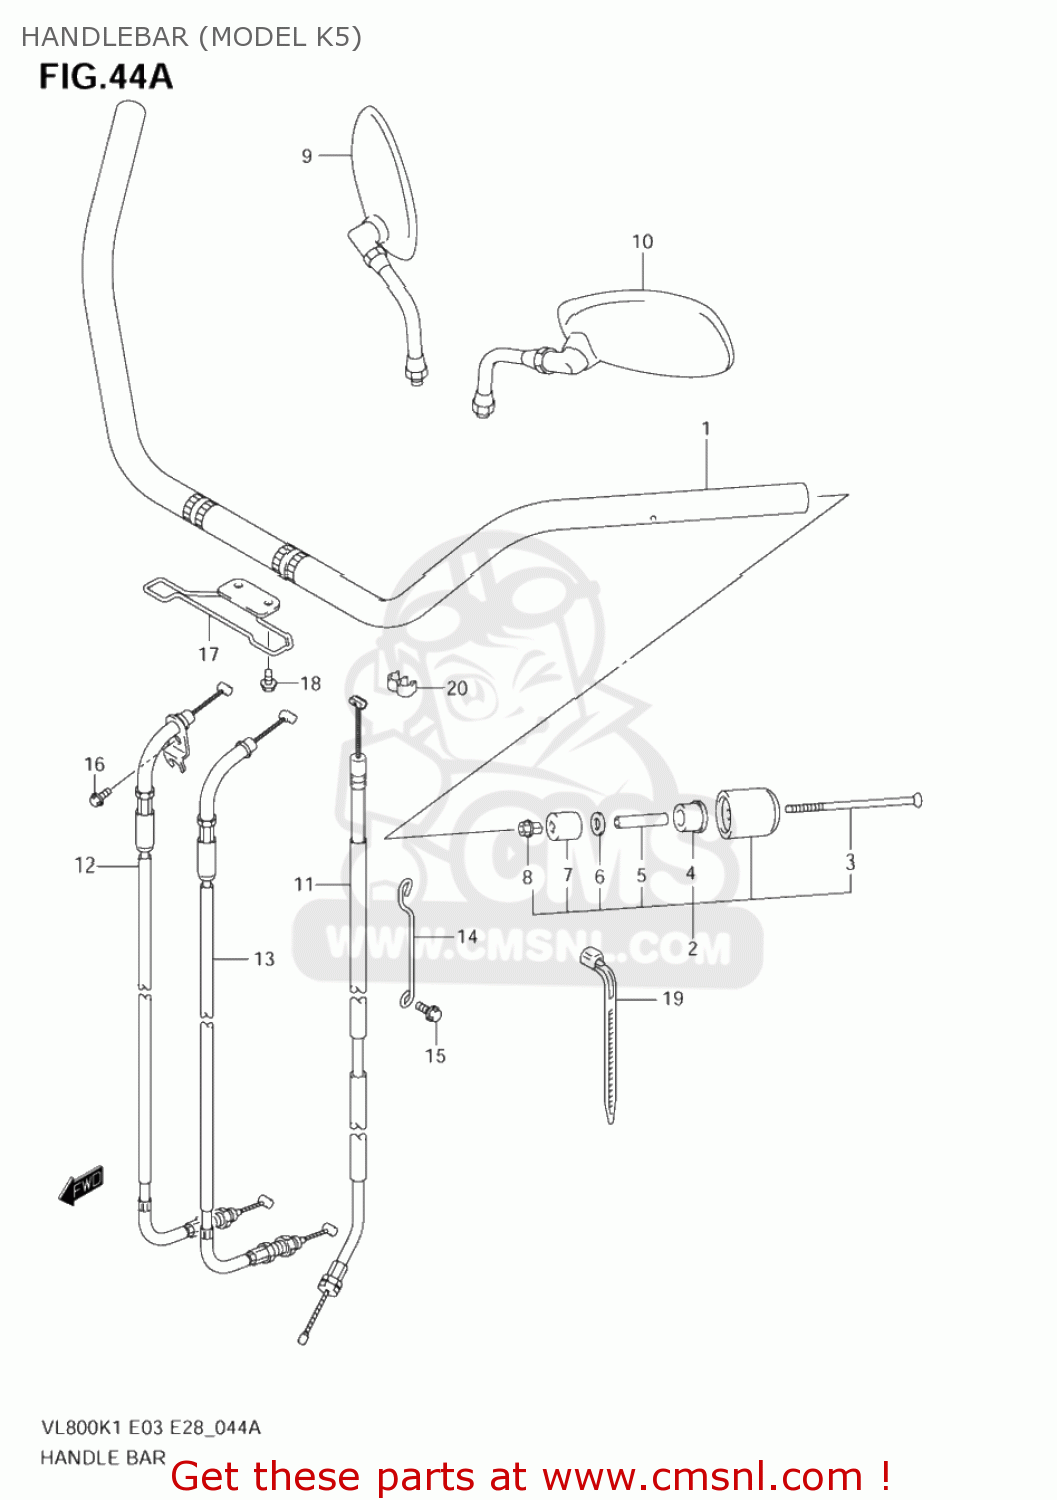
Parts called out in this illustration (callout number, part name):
1	HANDLEBAR
2	BALANCER SET,H
3	SCREW(6X127)
4	EXPANDER,HANDLE BALANCER NO.2
5	SPACER,EXPANDER
6	WASHER(6.5X16X4)
7	EXPANDER,HANDLE BALANCER
8	NUT,HANDLE BAL
9	MIRROR ASSY,RE
10	MIRROR ASSY,RE
11	CABLE ASSY,CLUTCH
12	CABLE ASSY,THROTTLE NO.1
13	CABLE ASSY,THROTTLE NO.2
14	GUIDE,THROTTLE CABLE
15	SCREW(5X10)
16	BOLT
17	GUIDE,CABLE
18	BOLT
19	CLAMP(L:190)
20	CLAMP
